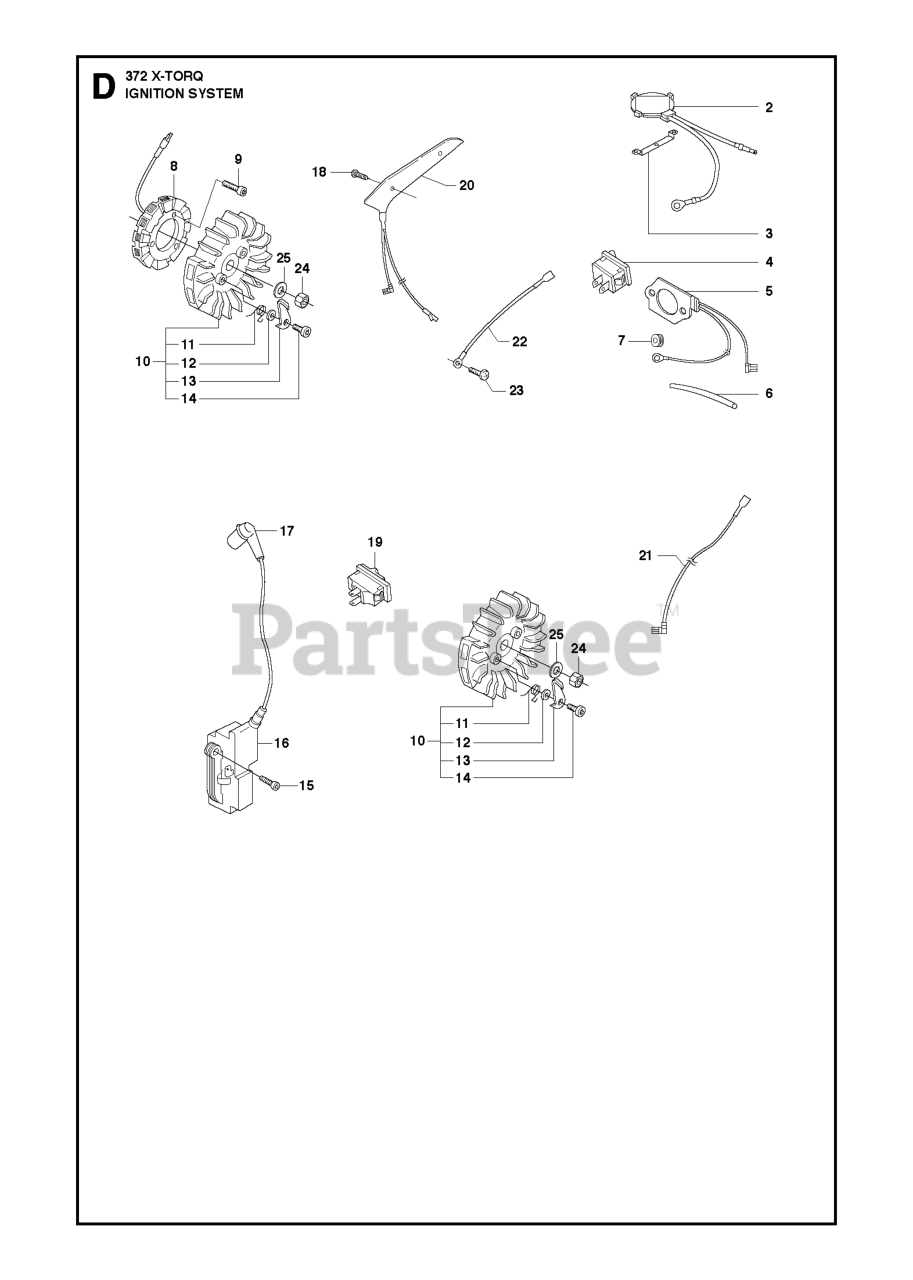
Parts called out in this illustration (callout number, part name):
2	THERMOSTAT
3	HOLDER
4	SWITCH
5	FOIL ELEMENT
6	TUBE
7	GROMMET
8	GENERATOR
9	SCREW
10	FLYWHEEL
14	SCREW M5X14
15	SCREW IHSCM M5X20 12.9 TBO SE
16	IGNITION MODULE
17	SPARK PLUG CONN. KIT
19	START/STOP SWITCH
20	PLATE (G)
25	WASHER 8.4X16
